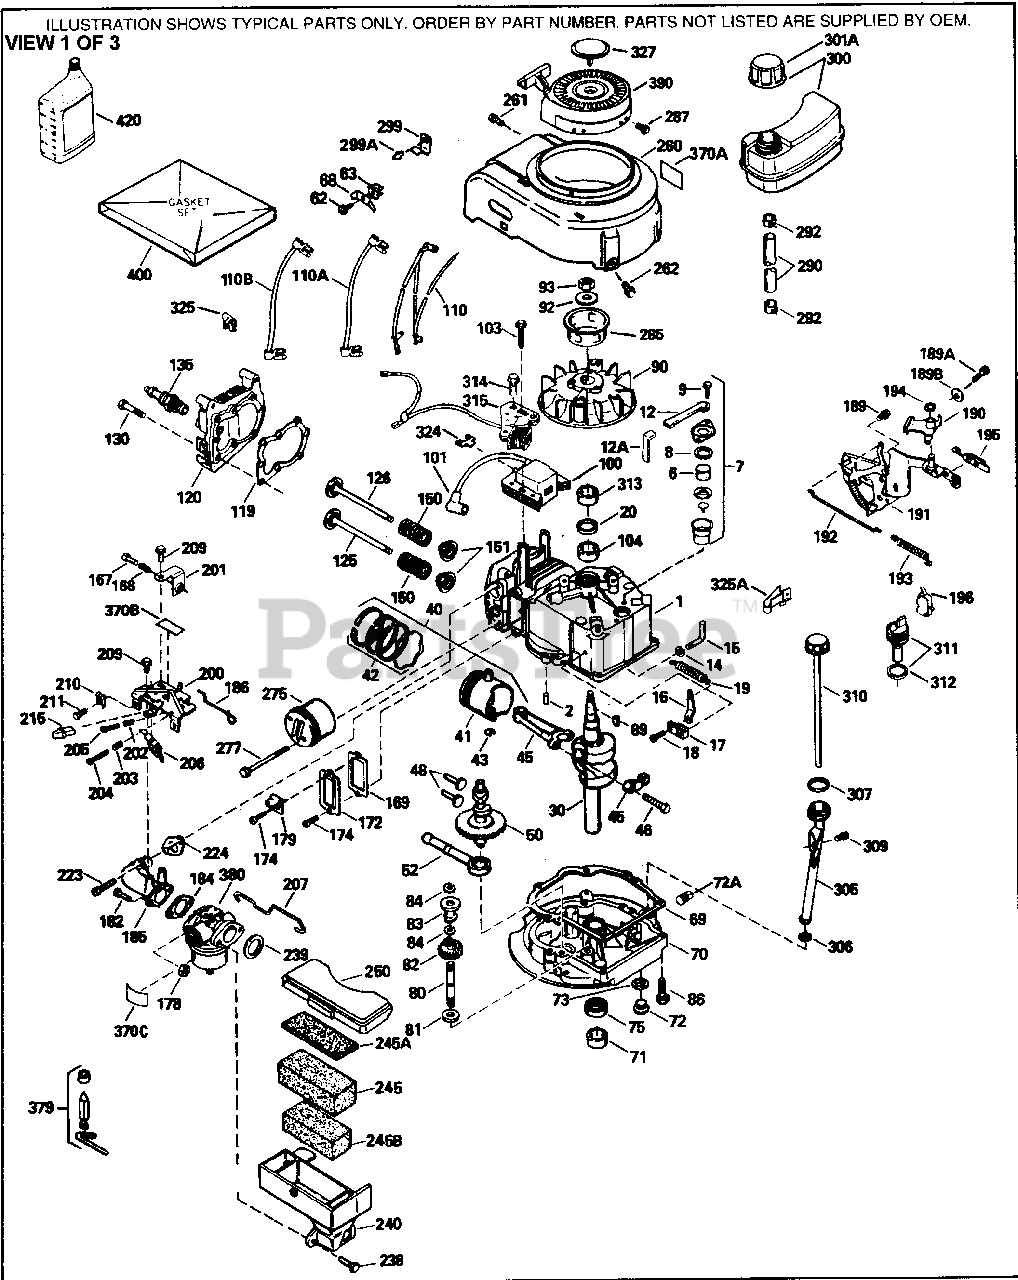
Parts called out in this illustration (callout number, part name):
1	"Cylinder (Incl. 2 & 20) (2-5/8" Bore)
2	Dowel Pin
6	Element, Breather
7	Breather Assy. Incl. 6, 8, 9, 12 & 1 2A
8	* Gasket, Breather
9	Screw, 10-24 x 9/16"
12	Tube, Breather
12A	Elbow, Breather tube
14	Flat Washer
15	Rod, Governor (Incl. 14)
16	Lever, Governor
17	Clamp, Governor lever
18	Screw, 8-32 x 5/16"
19	Spring, Extension
20	Seal, Oil
30	Crankshaft
40	Piston, Pin & Ring Set (Std.) 2-5/8" Bore
40	Piston, Pin & Ring Set (.010" OS)
40	Piston, Pin & Ring Set (.020" OS) (In cl. 41, 42 & 43)
41	Piston & Pin Assembly (Std.) (Incl. 4 3) 2-5/8")
41	Piston & Pin Assembly (.010" OS) (Inc l. 43) OS)
41	Piston & Pin Assembly (.020" OS) (Inc l. 43) OS)
42	Ring Set (Std.) (2-5/8" Bore)
42	Ring Set (.010" OS)
42	Ring Set (.020" OS)
43	Piston Pin Retaining Ring
45	Rod Assy., Connecting (Incl. 46)
46	Bolt, Connecting rod
48	Valve Lifter
50	Camshaft
52	Oil Pump Ass'y.
69	* Gasket, Mounting flange
70	Flange Ass'y. Incl. 72, 72A, 73, 75 & 80
72	Plug, Oil drain (Incl. 73)
73	* Drain Plug Gasket Not req. W/plastic plug
75	Oil Seal
80	Shaft, Governor
81	Washer, Flat
82	Gear Assy., Governor (Incl. 81)
83	Spool, Governor
84	Retaining Ring
86	Screw, 1/4-20 x 1-1/4"
89	Flywheel Key (also available in Packa ged Part #740007B)
90	Flywheel
92	Washer, Belleville
93	Nut, Flywheel
100	Solid State Ignition
101	Cover, Spark plug
103	Screw, Torx T-15, 10-24 x 1"
110	Ground Wire
119	* Gasket, Head
120	Head, Cylinder
125	Intake Valve (Std.) (Incl. 151) (Conv entional Ports)
125	Exhaust Valve (1/32" OS) (Incl. 151) (Conventional Ports)
126	Exhaust Valve (Std.) (Incl. 151) (Con ventional Ports)
126	Exhaust Valve (1/32" OS) (Incl. 151) (Conventional Ports)
130	Screw, 5/16-18 x 1-1/2"
135	Resistor Spark Plug (RJ19LM) also ava ilable in Packaged Part #740081
150	Spring, Valve
151	Cap, Lower valve spring
169	Valve Cover Gasket
172	Cover, Valve spring box
174	Screw, 10-24 x 1/2"
178	Nut & Lock Washer 1/4-28
182	Screw, 1/4-28 x 7/8"
184	* Gasket, Carburetor
185	Pipe, Intake (Incl. 224)
186	Link, Governor spring
189	Screw, 1/4-20 x 3/8"
190	Lever, Brake
191	Bracket Assy., S.E. Brake (Incl. 195)
192	Link, Control
193	Spring, Extension
194	Ring, Retaining
195	Terminal Assy.
200	Control Bracket (Incl. 202 thru 206)
202	Spring, Compression
203	Spring, Compression
204	Screw, 5-40 x 7/16"
205	Screw, 6-32 x 21/32"
207	Link, Throttle
209	Screw, 10-24 x 9/16"
215	Knob, Speed control
223	Screw, 1/4-20 x 1"
224	* Gasket, Intake pipe
238	Screw, 10-32 x 49/64"
239	* Gasket, Air cleaner
245	Air Filter (Paper) (also available in Packaged Part #740095 (Qty.2))
246D	Filter, Pre-Air (Optional)
250A	Air Filter Cover (Craftsman)
260	Housing, Blower
261	Screw, 10-24 x 9/16"
262	Screw, 1/4-20 x 15/32"
275	Muffler (Incl. 277)
277	Screw, 1/4-20 x 2-1/4" Use as requir ed
285	Hub, Starter
287	Screw, 8-32 x 1/2"
290	Fuel Line (Braided 16") (40 cm) Use a s req.
290	Fuel Line (Braided 32") (81 cm) Use a s req.
290	Fuel Line (Epichlorohydrin 6-3/4") 1 7 cm
290	Fuel Line (8.62") as req.)
292	Fuel Line Clamp
301A	Fuel Cap (Red)
305	Oil Fill Tube
306	Gasket, Oil fill tube
307	"O" Ring
309	Screw, 10-32 x 1/2"
310	Dipstick
313	Spacer, Flywheel key
327	Starter Plug
370A	Decal, Instruction
370C	Control Decal
370G	Decal, Instruction (Optional)
379	Inlet Needle, Seat & Clip Ass'y.
380	Carburetor (Incl. 184) (Refer to Divi sion 5, Section A, page A2-6 or Fiche 8A, Grid E-9for breakdown)
390	Rewind Starter Refer to Division 5, S ection C, page 34 or Fiche 8A, Grid G -5 for breakdown
400	* Gasket Set (Incl. items marked *)
420	SAE 30, 4-Cycle Engine Oil (Quart)
999	Summer Maintenance Kit (incl. Oil, Sp ark Plug, Air Cleaners (2), & Ultra-F resh)
